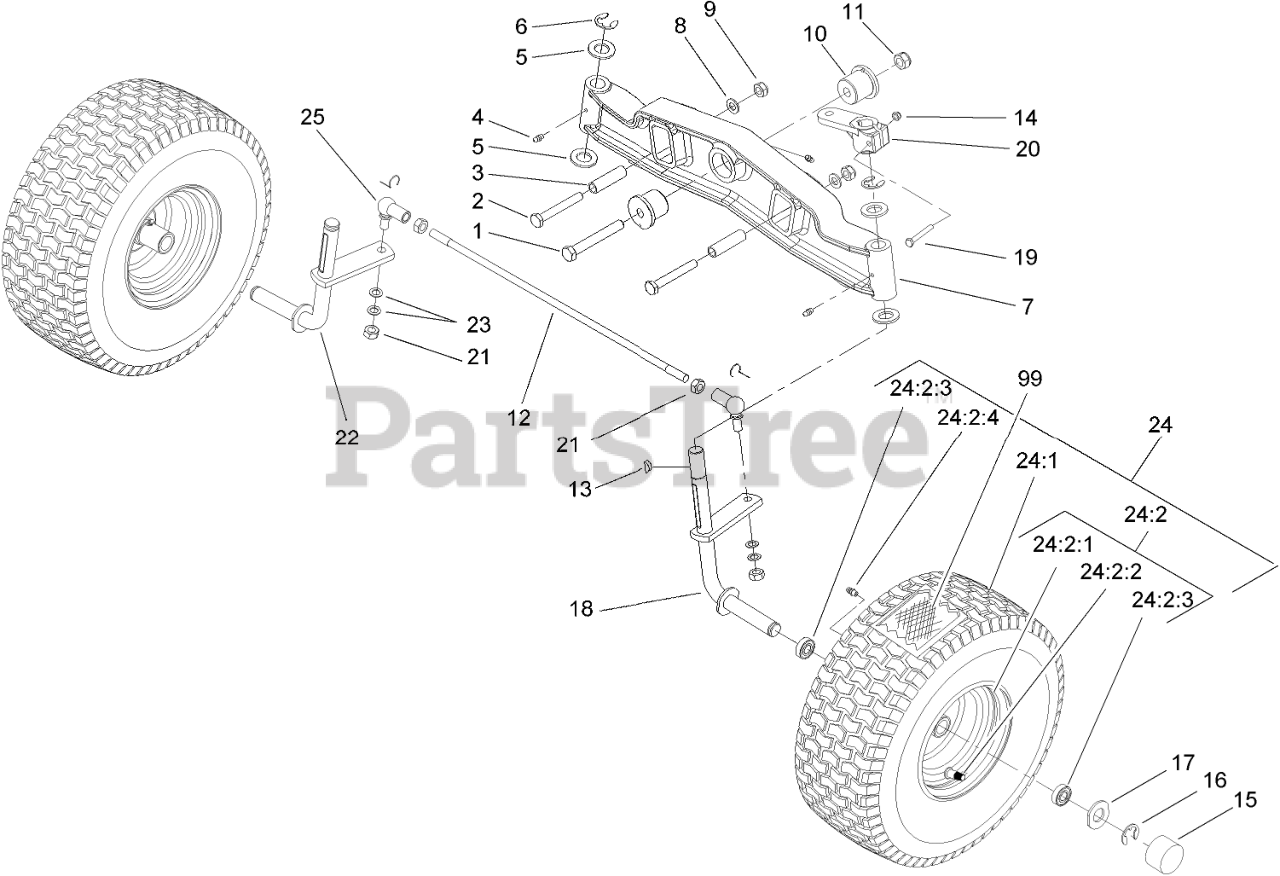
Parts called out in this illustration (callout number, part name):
1	SCREW-HH
2	SCREW-HH
3	SPACER
4	FITTING-GREASE
5	WASHER-FLAT
6	CLIP-SPRING
7	AXLE-FRONT
8	WASHER-FLAT
9	NUT-LOCK, NI
10	BUSHING-AXLE, FRONT
11	NUT-LOCKING, SELF
12	ROD-TIE, FRONT AXLE
13	KEY-WOODRUFF
14	NUT-LOCK
15	CAP-HUB
16	CLIP-SPRING
17	RETAINER-CAP, HUB
18	SPINDLE-LH
19	SCREW-HH
20	LEVER-SPINDLE, STEERING
21	NUT-LOCK, NI
22	SPINDLE-RH
23	Washer
24	TIRE and WHEEL ASM
24:2	WHEEL ASM
24:2:1	RIM
24:2:2	Valve-Tire
24:2:3	BEARING-WHEEL
24:2:4	Fitting-Grease
25	JOINT-BALL, ANGLE
99	TUBE-INNER
